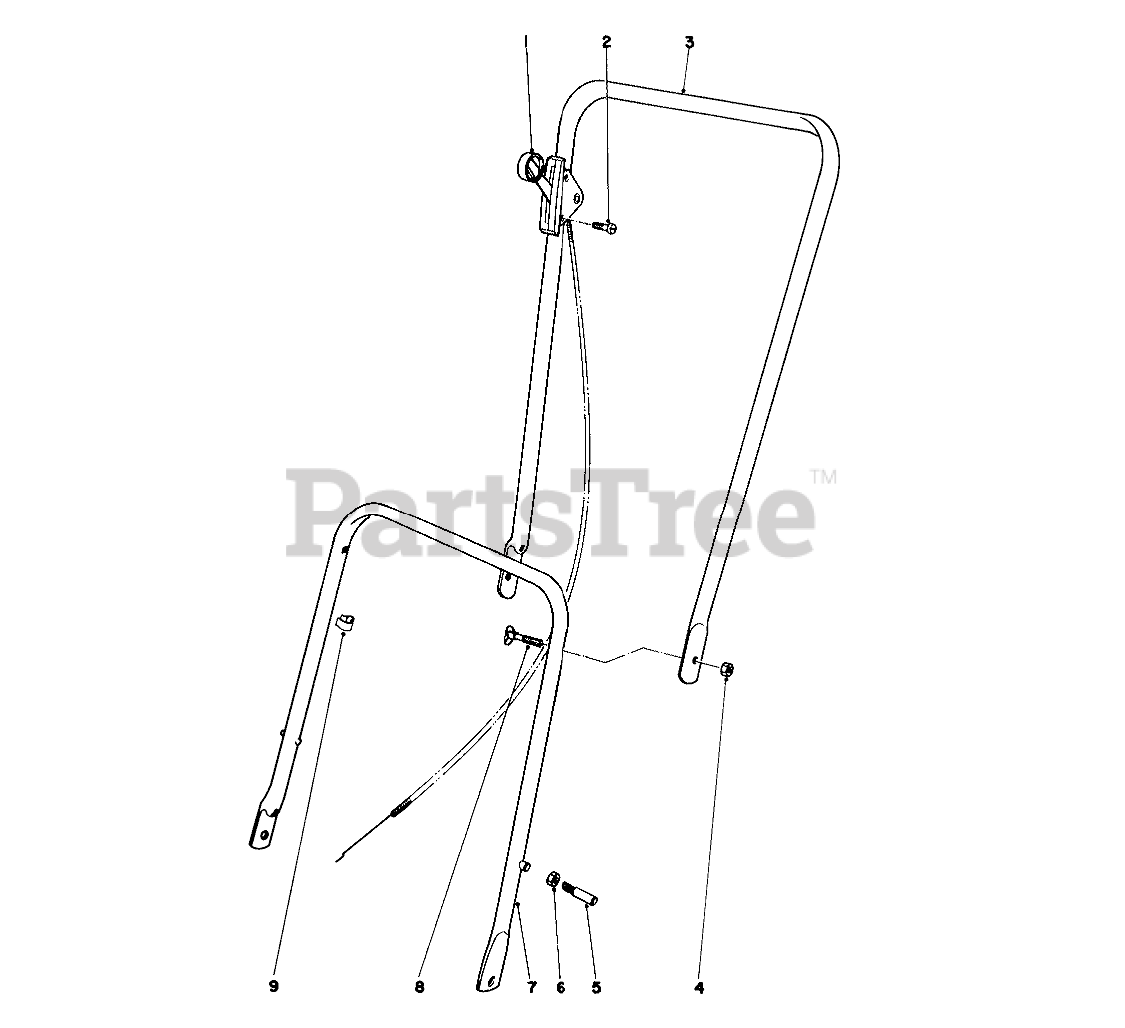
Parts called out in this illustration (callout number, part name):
1	Control-Throttle
2	10-24 X 1 PAN HD SCR
3	Handle-Upper
4	Nut
5	HANDLE PIN
6	Nut
7	LWR HANDLE STAKED ASM
8	1-1/4 LG HANDLE SCREW
9	CONTROL WIRE CLIP
